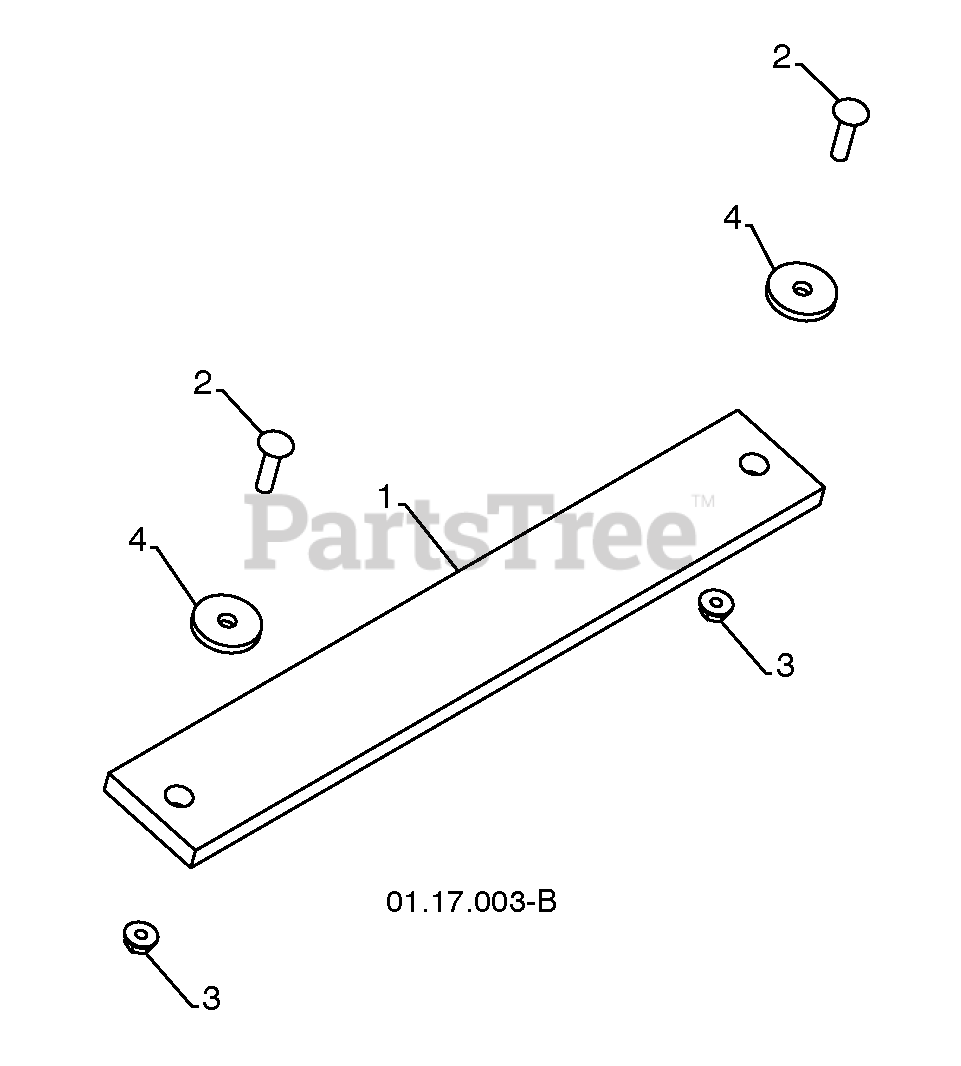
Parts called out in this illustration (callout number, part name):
1	WEIGHT BAR
2	CARRIAGE BOLT 5/16-18 X 1.25
3	NUT 5/16-18
4	WASHER
